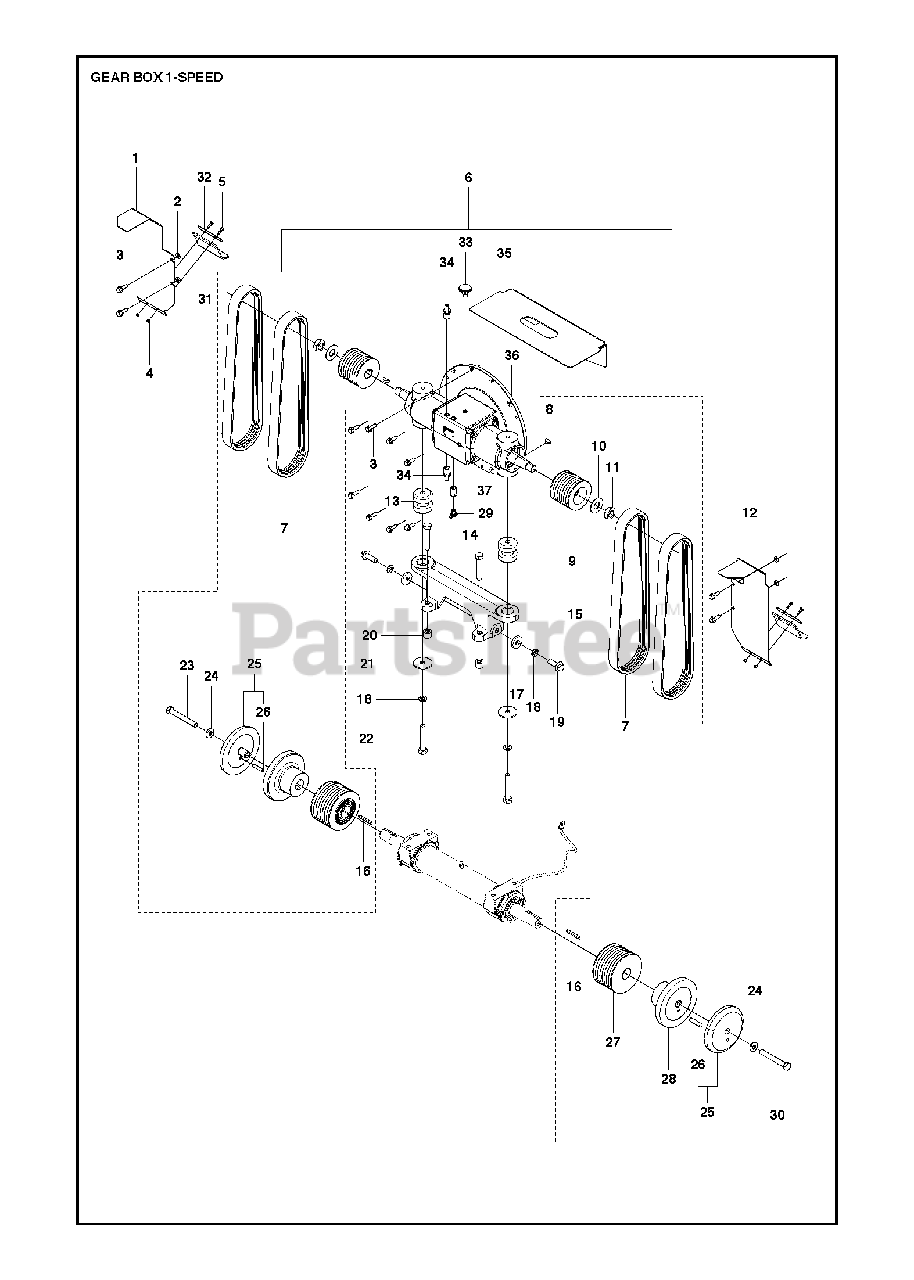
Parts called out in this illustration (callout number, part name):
2	WASHERRight Side
4	HEXAGON LOCKING NUT
9	PULLEY"26"", 30"", 36"", 42"""
13	SILENBLOC E/FS1200T PO
23	SCREW"20"", 26"", 30"", 36"""
26	PIN"20"", 26"", 30"""
30	SCREW"20"", 26"", 30"", 36"""
